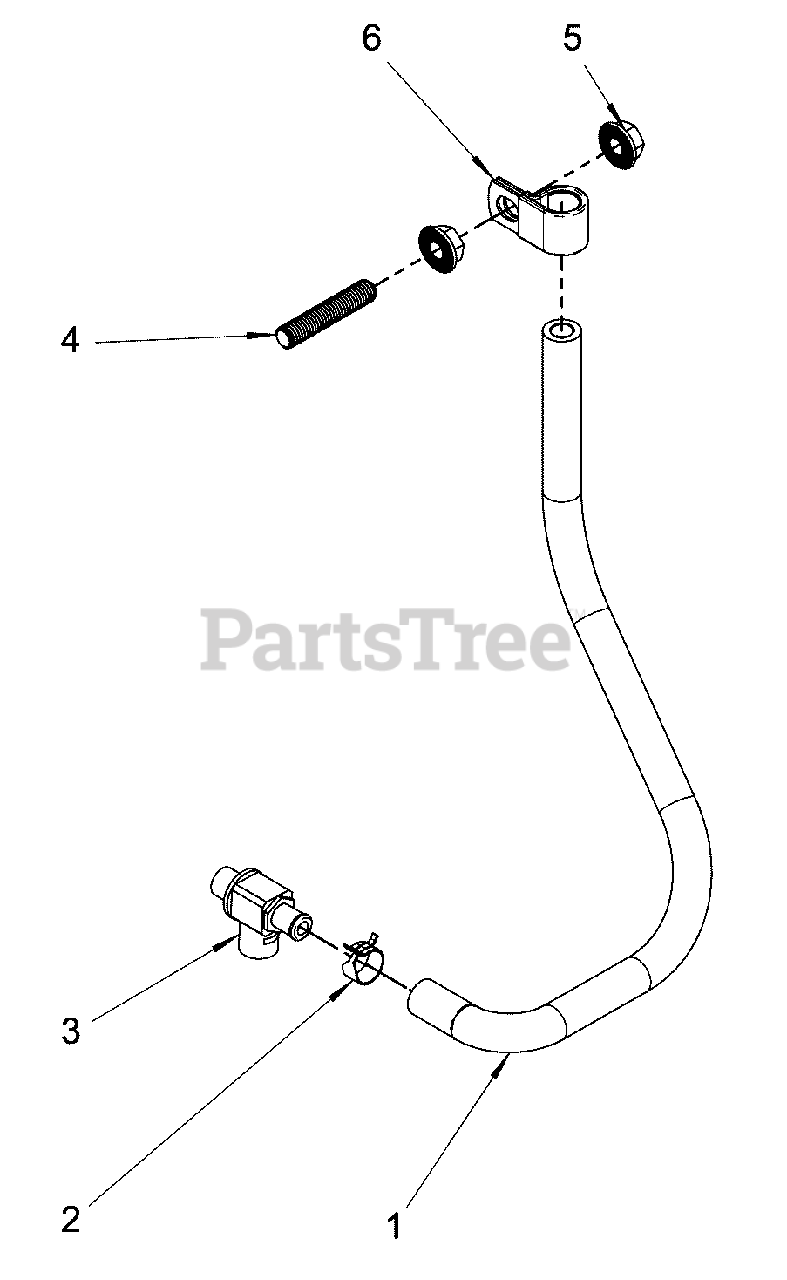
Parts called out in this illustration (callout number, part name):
1	* FUEL HOSE
2	* CLAMP
4	* STUD
5	* NUT
6	* CLAMP
